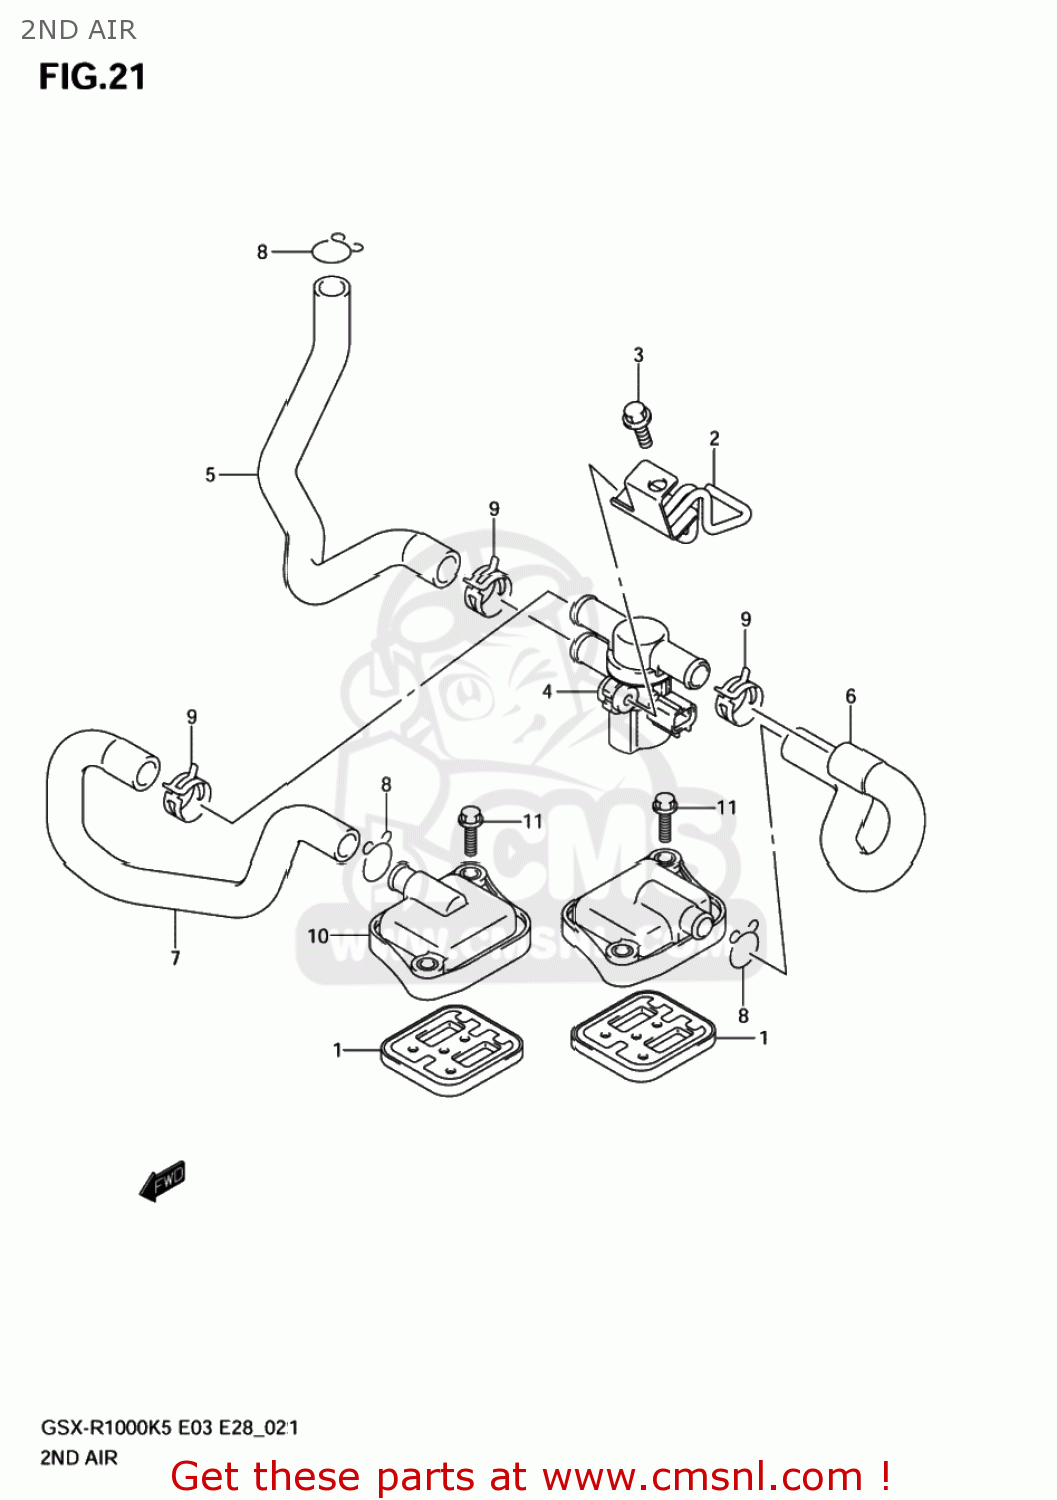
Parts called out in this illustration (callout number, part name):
1	VALVE ASSY,2ND
2	BRACKET,2ND AIR VALVE
3	BOLT
4	VALVE ASSY,AIR CUT
5	HOSE,2ND AIR CLEANER
6	HOSE,AIR CUT VALVE,L
7	HOSE,AIR CUT VALVE,R
8	CLIP
9	CLIP
10	COVER,2ND AIR REED VALVE
11	BOLT(6X20)
